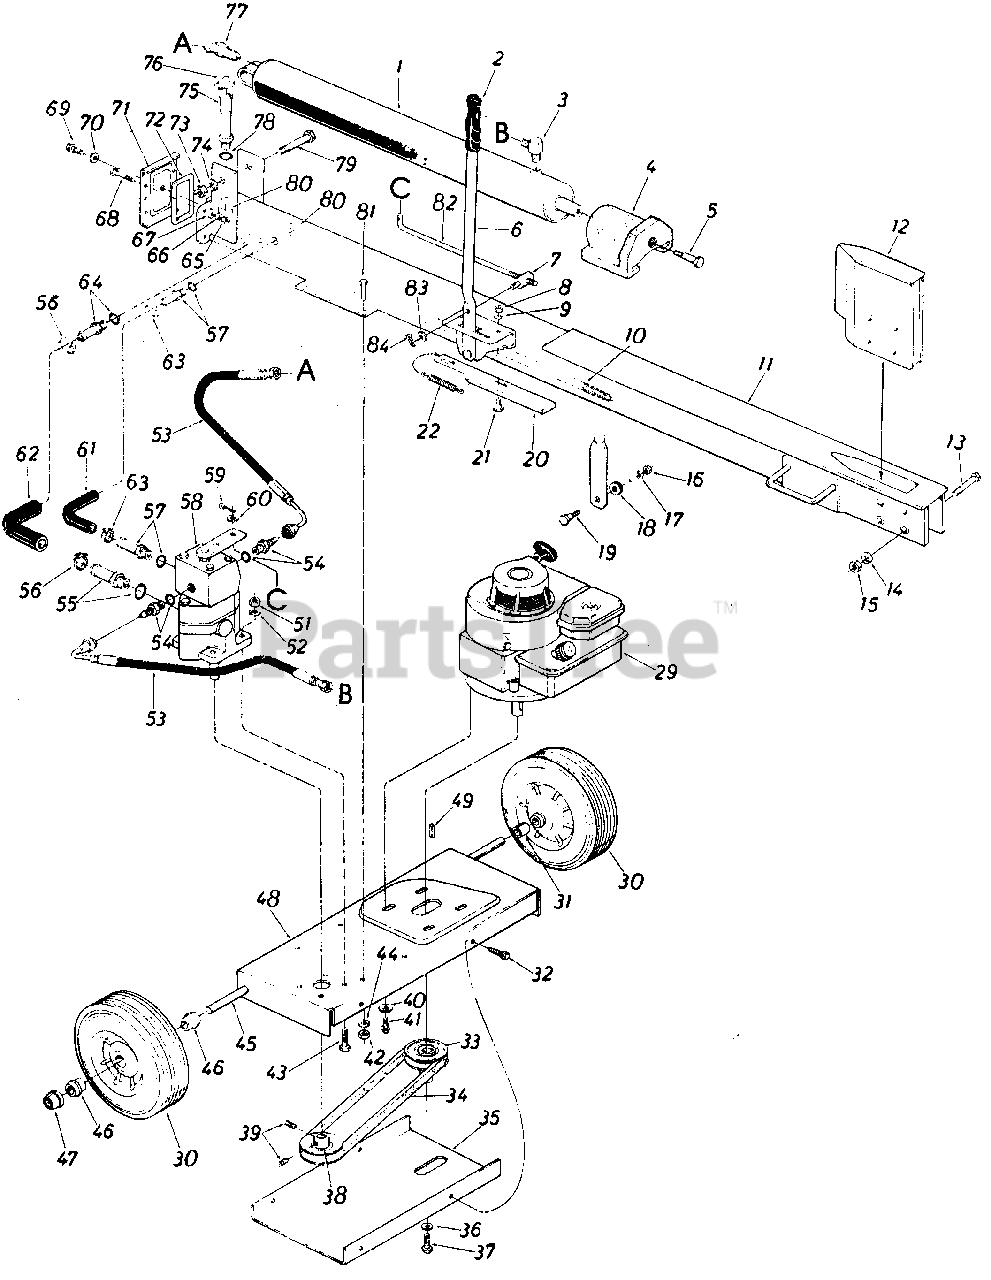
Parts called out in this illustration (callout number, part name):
1	2-1/2" Cylinder Ass'y. Comp.
2	Grip
3	90ø Elbow Adapter
4	Pusher Plate
5	Shoulder Bolt 5/8" Dia. x .660" Lg. 1/2-13 Thd.
6	Engagement Handle
7	Adjustment Ferrule
8	Hex Nut 5/16-18 Thd.*
9	L.-Wash. 5/16" I.D.*
10	Strainer Tube Ass'y.
11	Oil Tank Ass'y. Comp
12	Wedge Ass'y.
13	Hex Bolt 5/8-18 x 3.50" Lg. Grade 5
14	L.-Wash. 5/8" I.D.
15	Hex Nut 5/8-18 Thd.*
16	Hex Nut 3/8-16 Thd.*
17	L.-Wash. 3/8" I.D.*
18	Rubber Wash.
19	Shoulder Bolt .498 x .340
20	Engagement Brk't.
21	Shoulder Bolt .437" Dia. x .180" Lg.
22	Extension Spring .50" O.D. x 4.25" Lg.
29	Engine-B & S
30	Wheel Ass'y. Comp. 10.0" x 2.75
31	Sleeve.632" I.D. x .875" O.D. x .90" Lg.
32	Hex Wash. Hd. Self Tap. Scr. 1/4-20 x .50" Lg.
33	1/2" V-Pulley 7/8" I.D. x 7/8" I.D. x 3-1/4" O.D.
34	"V"-Belt (4L) 1/2" V x 30" Lg.
35	Belt Cover
36	L.-Wash. 5/16" I.D.*
37	Hex Bolt 3/8-24 x 1.0" Lg.*
38	1/2 (4L) "V"-Pulley 5/8" I.D. x 3-1/2" O.D.
39	Set Scr. 1/4-28 x .25" Lg.
40	Bell.-Wash. .40" I.D. x .88" O.D.
41	Hex Wash. Hd. TT-Tap Scr. 3/8-16 x .87" Lg.
42	Hex Nut 5/16-24 Thd.*
43	Hex Bolt 5/16-18 x 1.00" Lg.*
44	L.-Wash. 5/16" I.D." I
45	Axle Shaft 5/8" Dia. x 25.5" Lg.
46	Flange Brg. w/Flats .631" I.D.
47	Push Cap 5/8" Dia. Rod
48	Frame Engine
49	Sq. Key 3/16" x 3/16" x 1.50" Lg.*
51	Hex Nut 5/16-18 Thd.*
52	L.-Wash. 5/16" I.D.*
53	High Pressure Hose l
54	Adapter-or Boss to MJIC 9/16-18 to 7/16-20
55	Adapter 3/4" Tubing to 3/4-16 M-Boss
56	Hose Clamp 5/8" I.D.
57	Adapter 1/2" Tube 9/16-18 or M-Boss
58	Valve Ass'y.
59	Cotter Pin 3/32" Dia. x .75"
60	Fl .-Wash. 344" I.D. x .6 2" O.D. x .063
61	Return Hose.50" I.D.
62	Suction Hose.75" I.D.
63	Hose Clamp 1/4" I.D.
64	Adapter 1.0" Tube 1-1/1612 "O"-Ring
65	Hex Nut 5/16-18 Thd.*
66	L.-Wash. 5/16" I.D.*
67	Fl.-Wash. .343" I.D. x .687" O.D. x .062
68	Hex Bolt 5/16-18 x 1.50" Lg.*
69	Hex Hd. Tap Scr. 5/16"
70	Gasket
71	End Plate
72	Gasket
73	Hex Nut 3/4" Thd.*
74	L.-Wash. 3/4" I.D.*
75	Filler Tube Ass'y.
76	Oil Fill Cap
77	45ø Male Adapter 7/16-20 MJ-1/4-18 NP
78	"O"-Ring .92" I.D. x 1.16" O.D. x .116 Dia.
79	Hex Bolt 3/4" x 4.0" Lg.
80	Hex Nut 11/16-12 Thd.
81	Hex Bolt 5/16-24 x 1.00" Lg. Grade 5
82	Engagement Rod 16.75" Lg.
83	Fl.-Wash. .344" I.D. x .62" O.D. x .063
84	Hair Pin Cotter 5/16" Dia.
